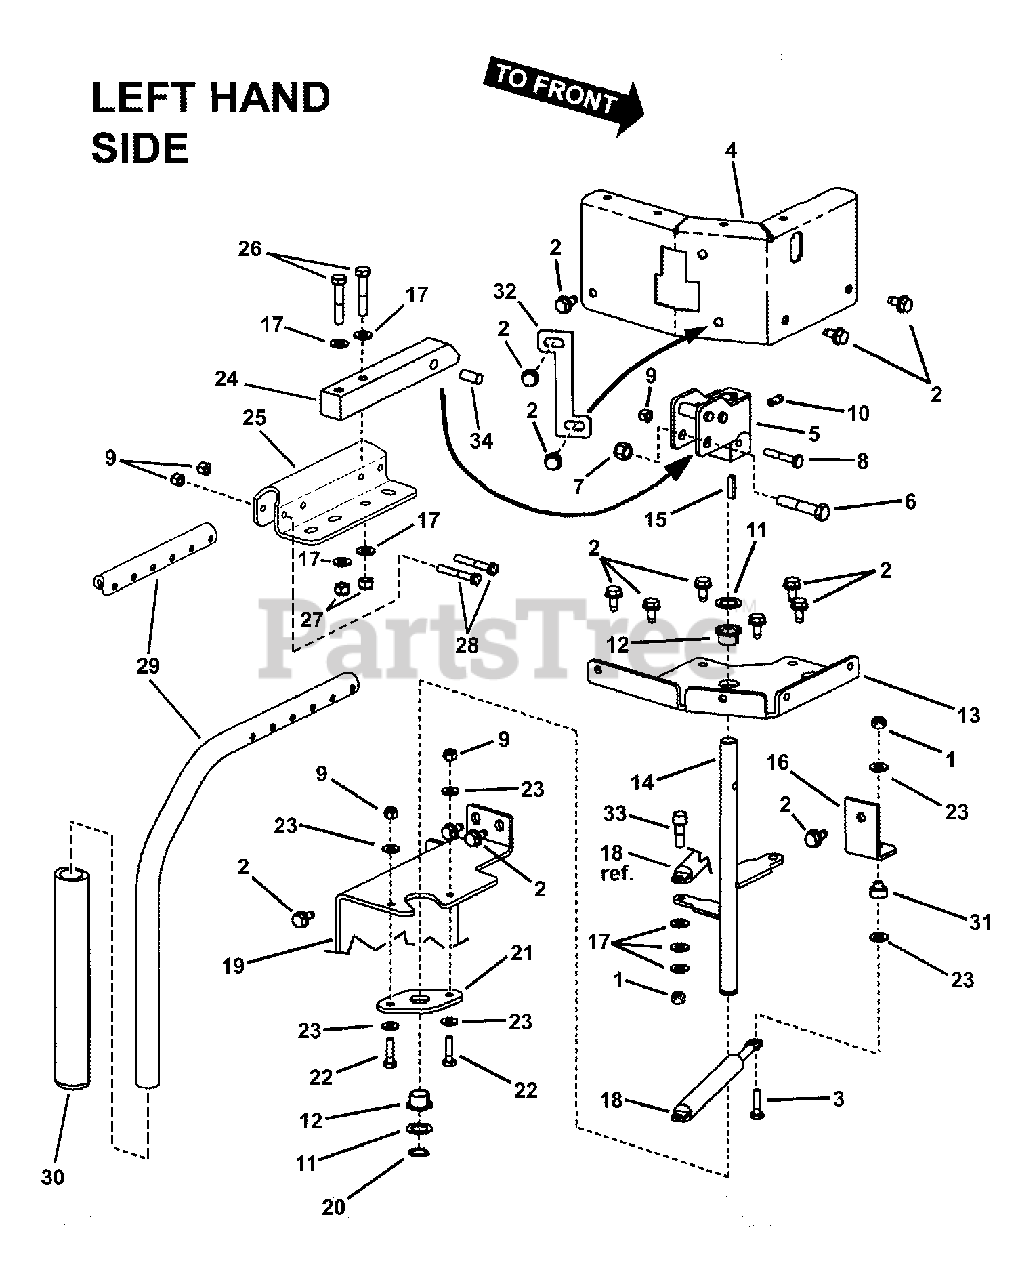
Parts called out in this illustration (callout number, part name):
1	NUT, 1/4-20 Hex Center Lock
2	SCREW, 5/16-18 x 5/8" Hex Washer Self-Tap
3	SCREW, 1/4-20 x 1-1/4" Hex Head Cap
4	LIMITER BRACKET, Left Hand
5	WELDMENT, Mounting Hub
6	BOLT, 3/8-16 X 2, GD5, CZ
7	NUT, 3/8-16 HEX NYLON LOCK
8	SCREW, 1/4-20 x 1-1/2" Hex Head Cap GR 5
9	NUT, 1/4-20 HEX NYLON LOCK
10	SET SCREW, 5/16-18 Square Head w/Patch
11	WASHER, .64 I.D. x .99 O.D. x .05 Flat
12	BUSHING, Teflon Impregnated
13	BUSHING MOUNT PLATE, Left Hand
14	WELDMENT, Cross Rod, LH
15	KEY, 3/16" Square x 7/8" Long
16	BRACKET, Dampener Frame
17	WASHER, 5/16" Flat
18	CYLINDER, Dampener
19	CHANNEL, Mounting
20	RING, 5/8" External Retaining
21	MOUNTING PLATE, Left Hand Bearing
22	BOLT, 1/4-20 X 1" GD5 CZ
23	WASHER, .28 I.D. x .63 O.D. x .06 Thick Flat
24	MOUNTING ARM
25	BRACKET, Handle Adjustment
26	BOLT, 5/16-18 X 1-3/4 GD5 YZ
27	NUT, 5/16-18 HEX NYLON LOCK
28	BOLT, 1/4-20 X 1-3/4" GD5 YZ
29	HANDLEBAR
30	GRIP, Twin Stick
31	SPACER
32	BRACKET, Speed Control
33	SCREW, 1/4-20 Shoulder Socket Head
34	SPACER, .498 O.D. x 1.010" long
